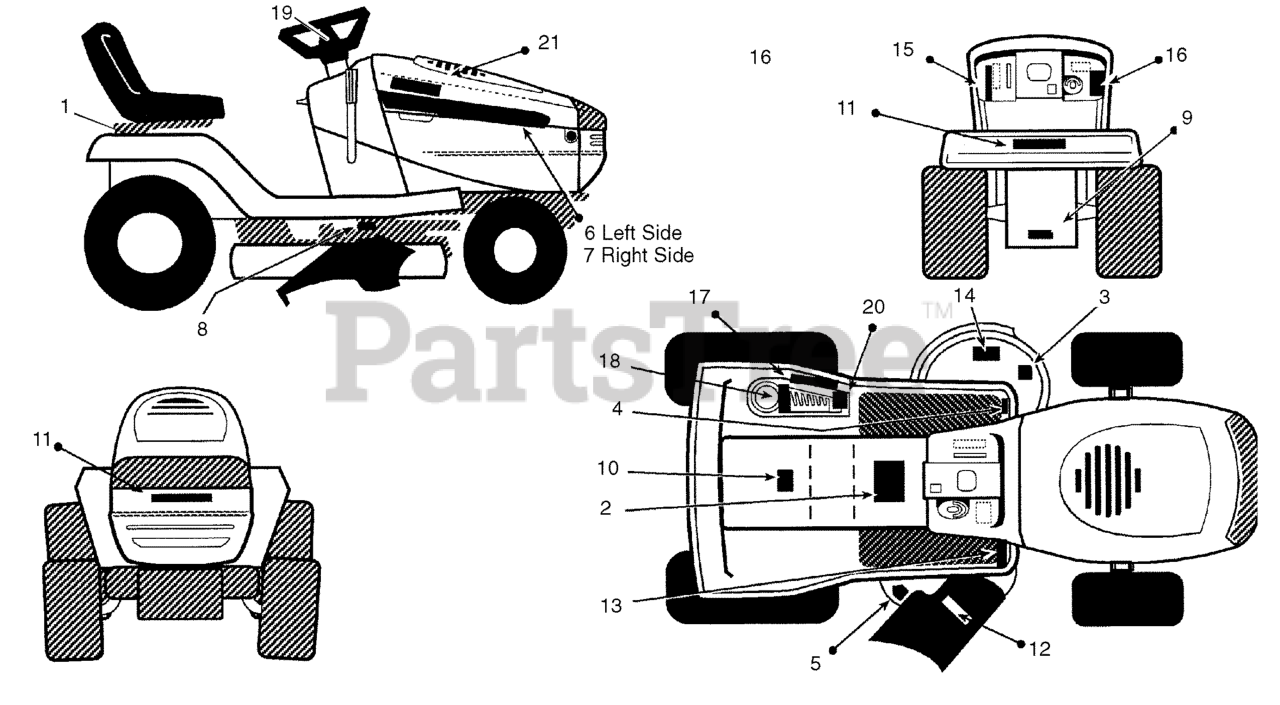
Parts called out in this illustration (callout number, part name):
1	DEKA (Battery)
2	Warning (Console - Center)
3	NO STEP (Mower Deck - Left Side)
4	Park / Brake
5	Cut Finger (Mower Deck -Right Side)
6	22/46 Auto Twin
7	22/46 Auto Twin
8	Gage Wheel Level
9	Warning Load Limit (Rear)
10	Auto Disconnect
11	Craftsman Logo
12	Mulch Kit Installed
13	Hydro Drive
15	Throttle, Twin
16	Ignition & Parking Brake
17	Lifter and Height Adjust
18	Cutting Height
19	Steering Wheel
20	Deck Level
21	Craftsman Nameplate
